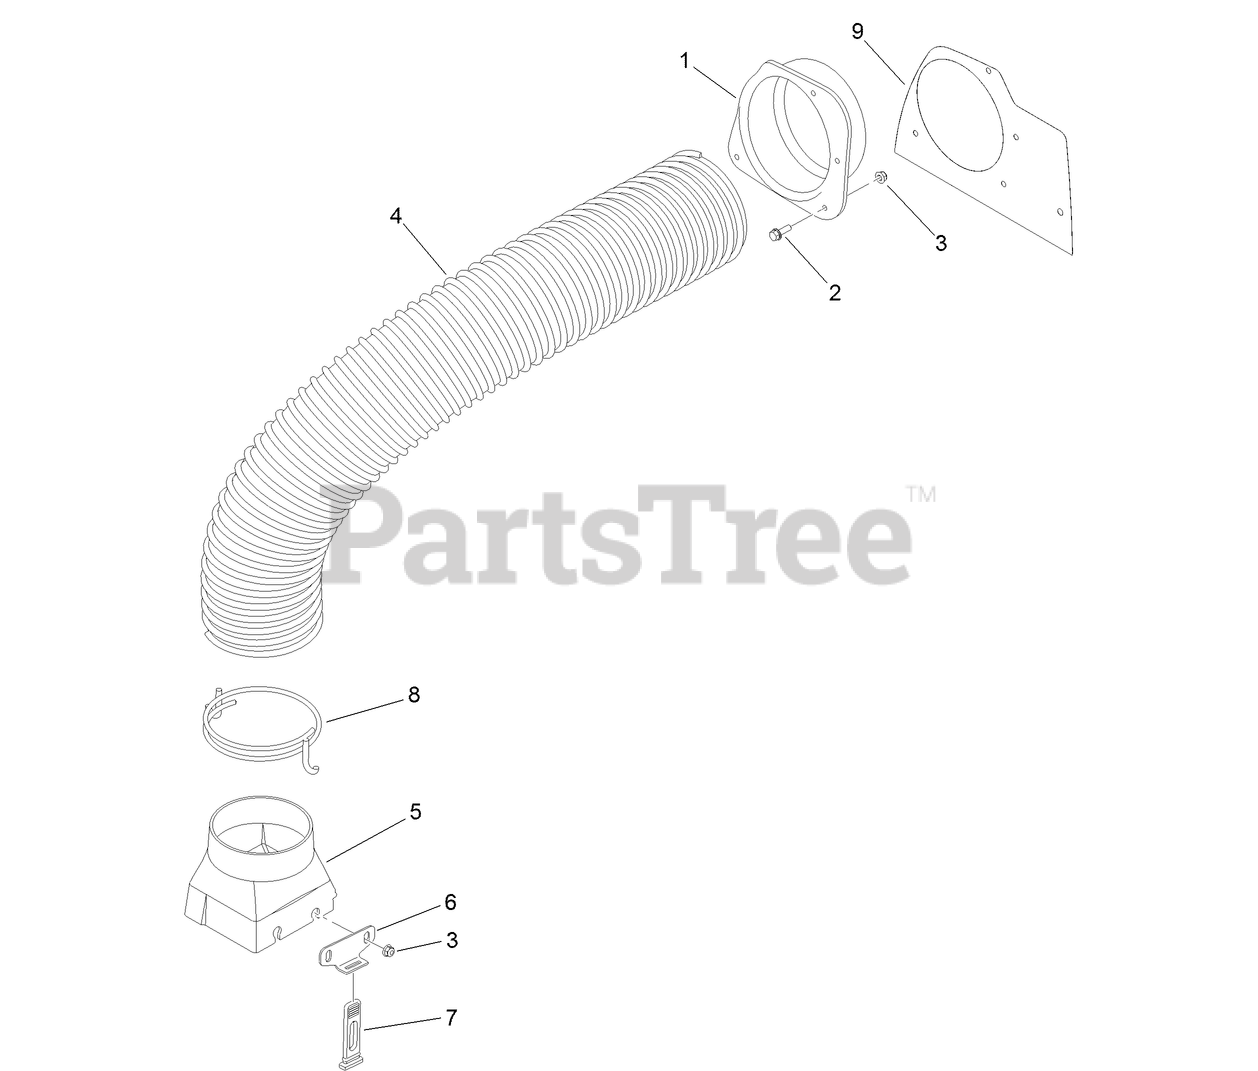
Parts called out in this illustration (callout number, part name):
1	ADAPTER-INLET, HOOD
2	SCREW-HHF
3	NUT-HF, NI
4	HOSE-FLEXIBLE
5	TRANSITION-BLOWER
7	STRAP-HOLD DOWN
8	CLAMP-HOSE, BAGGER
9	TEMPLATE-HOOD, BAGGER
